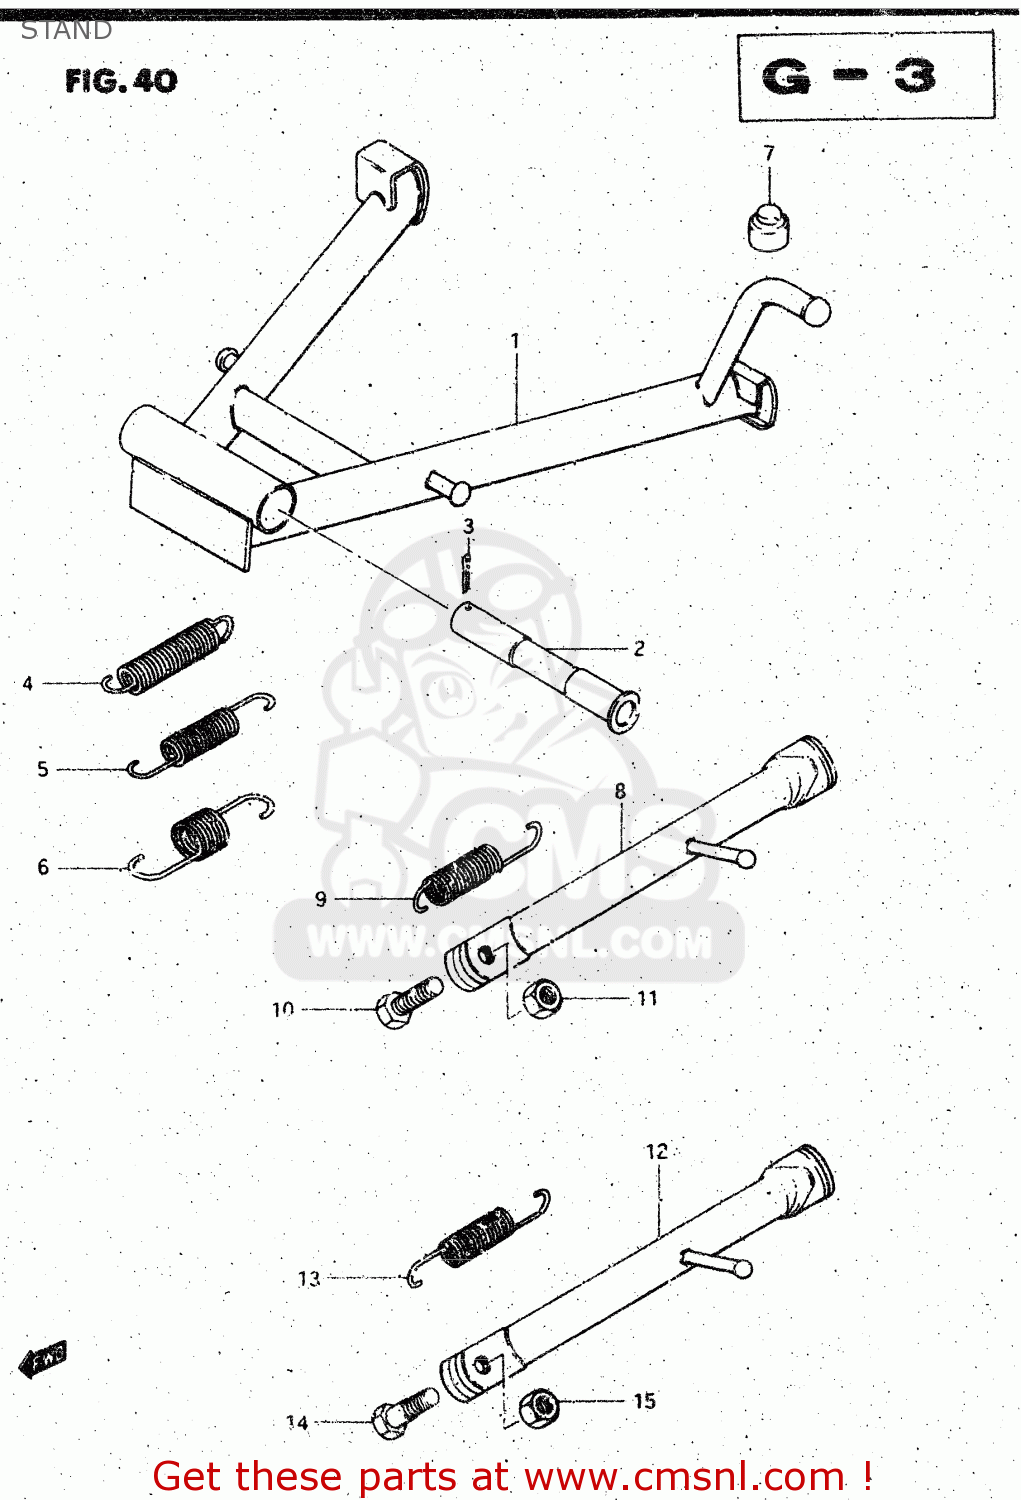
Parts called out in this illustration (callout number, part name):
1	STAND,CTR
2	SHAFT,CENTER STAND
3	COTTER PIN
4	SPRING
5	SPRING
6	SPRING
7	CUSHION
8	STAND,PROP
9	SPRING
10	BOLT(10X30)
11	NUT
12	STAND,PROP
13	SPRING
14	BOLT L:30
15	NUT
